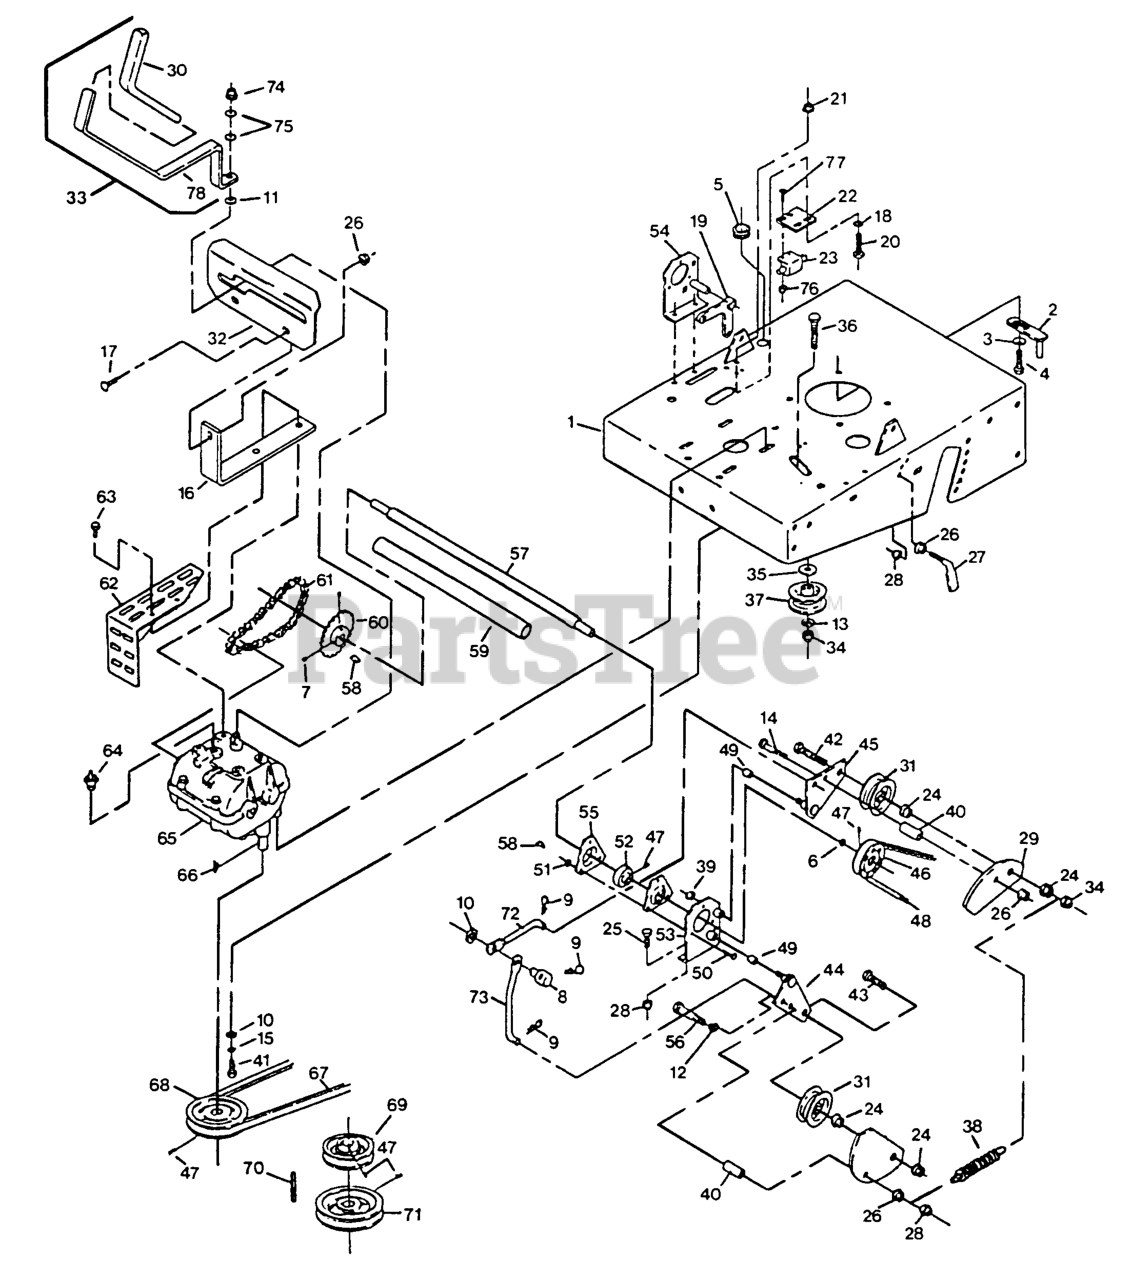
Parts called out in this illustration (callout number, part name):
2	GUIDE - BELT, 32
3	WASHER-SPRING
5	GROMMET
7	SCREW-SET
8	SWIVEL,SHORT ADJUSTING
9	PIN-COTTER
15	WASHER-LOCK
16	BRACKET-PLATE, SHIFT
19	BELLCRANK
22	BRACKET,SAFETY SWITCH
23	SWITCH-OPEN, NORMALLY
31	PULLEY,IDLER
37	IDLER,PULLEY
38	SPRING-IDLER
39	NUTTORQUE ZKPLT
44	ARM - IDLER
45	ARM - IDLER
47	SCREW-SET
48	BELT,COG
57	JACKSHAFT
61	CHAIN,DRIVE
64	SWITCH-START, NEUTRAL
67	BELT,TRANSMISSION
70	KEY,MACH 1/4X1/4X2-5/8
71	SHEAVE,BLADE DRIVE
72	LINKAGE,UPPR CALIPERPLT
73	LINKAGE,LOWER CALIPER RH
